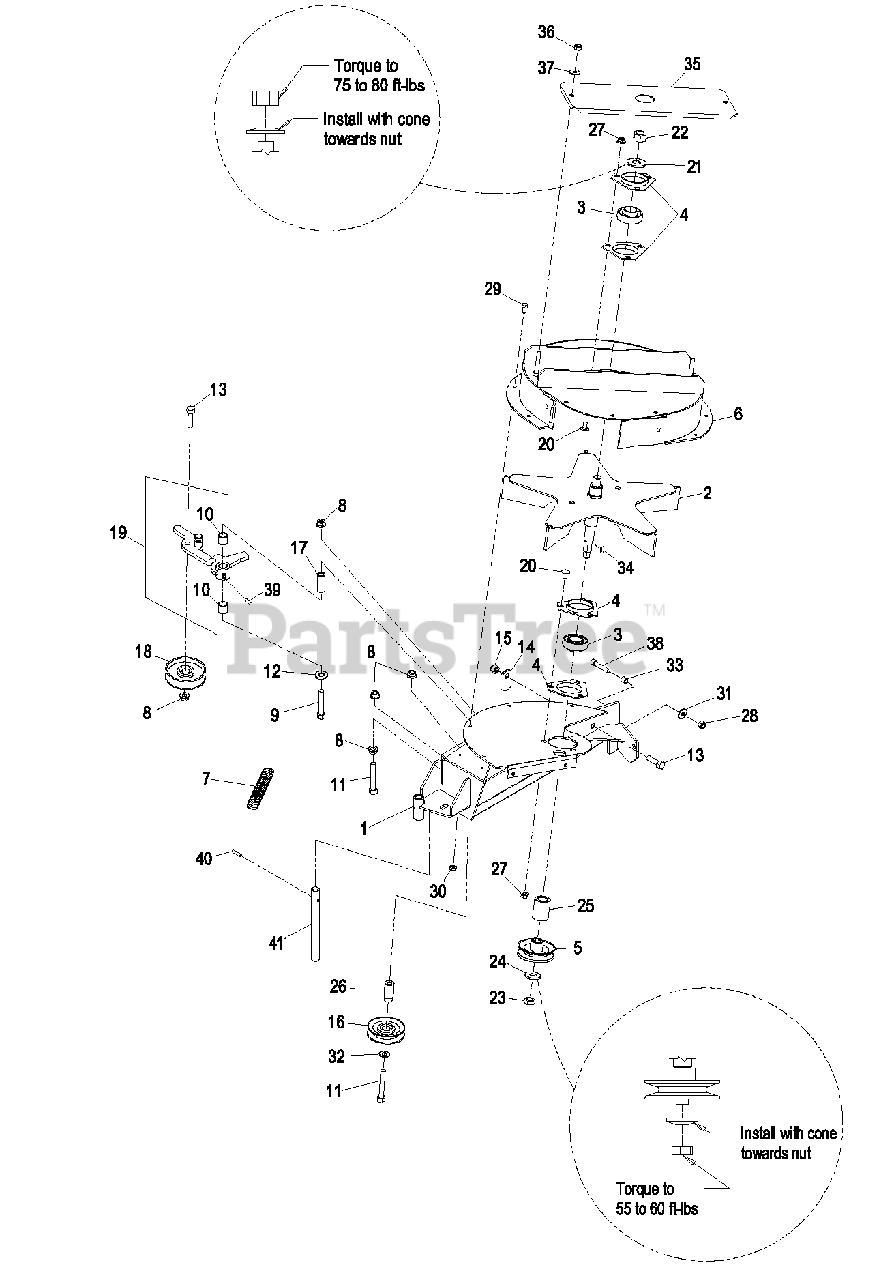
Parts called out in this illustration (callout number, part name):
1	WLD,BLOWER MOUNT
2	IMPELLER
3	BEARING
4	HOUSING-FLANGE
5	SHEAVE-BLOWER
6	ASM,UPPER HOUSING
7	SPRING-IDLER
8	NUT-HHF, WHIZ
9	SCREW-HSBH
10	BUSHING
11	BOLT-CARR
12	WASHER-FLAT
13	SCREW-HH
14	LATCH-CATCHER, GRASS
15	NUT-LOCK, NI
16	IDLER-INSIDE
17	BUSHING-PIVOT, IDLER
18	IDLER-FLAT
19	ASM, IDLER ARM - SERVICE
20	SCREW-CARR
21	WASHER-SPRING
22	NUT-HEX
23	NUT-JAM
24	WASHER-SPRING
28	NUT-HEX
29	SCREW-HH
31	WASHER-SPRING
32	WASHER-FLAT
33	BUSHING, LOCATOR
34	KEY-WOODRUFF
35	ASM, BEARING COVER
36	NUT-LOCK, NI
37	WASHER-FLAT
38	SCREW-HSH
39	FITTING-GREASE
40	PIN-ROLL
41	SHAFT-CATCHER, GRASS
